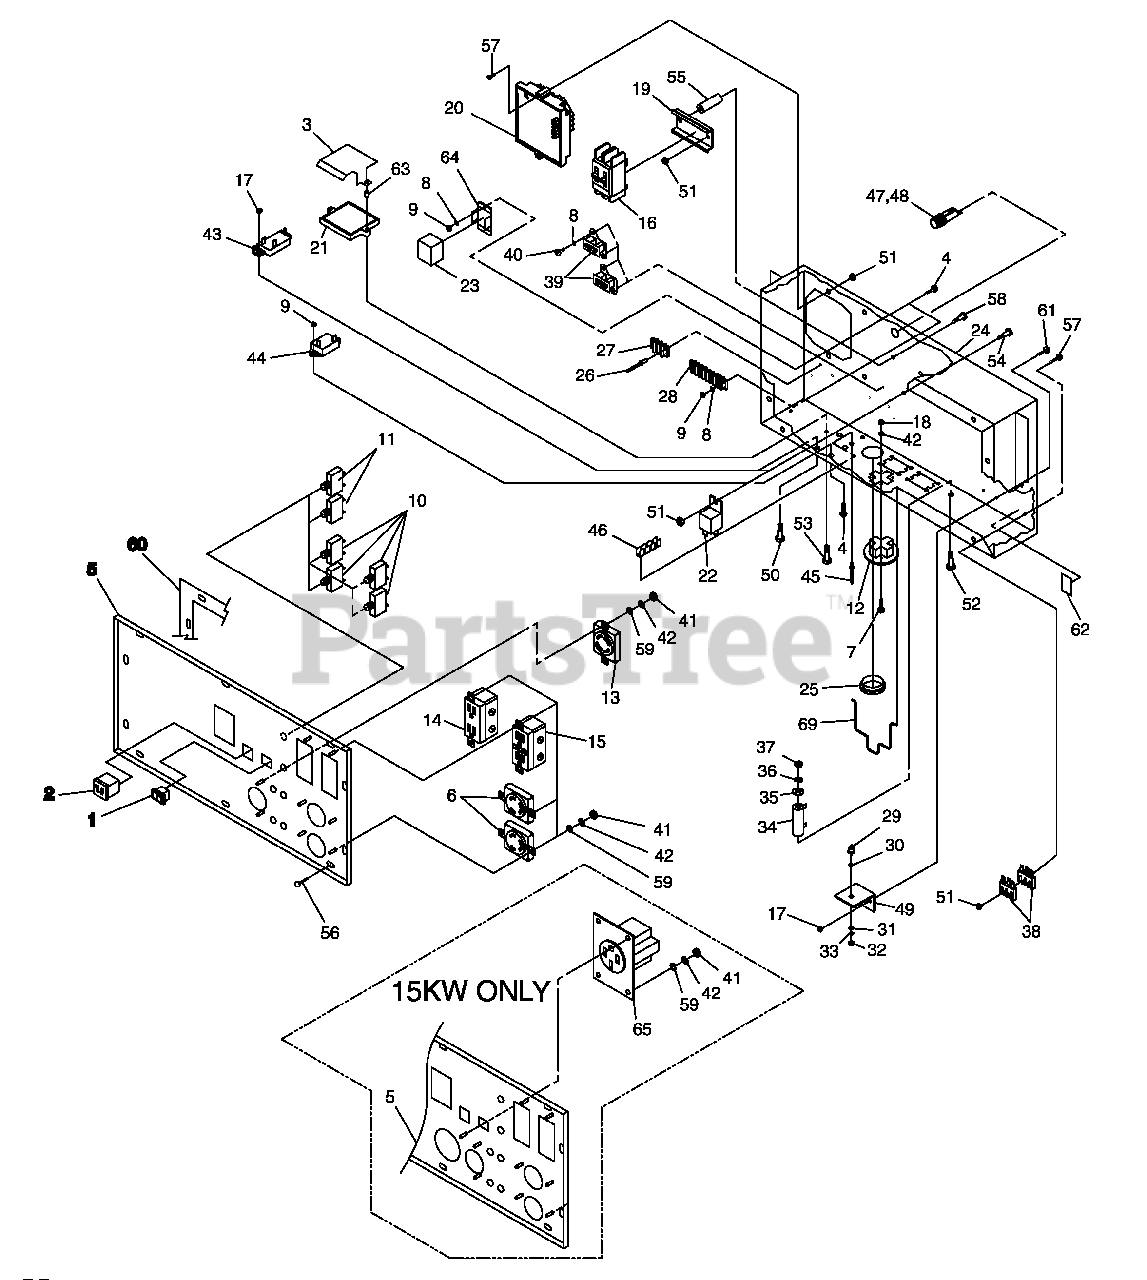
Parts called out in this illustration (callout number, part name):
1	SWITCH, ROCKER -/0
2	OUTLET, 12VDC SNAP
3	COVER, GOVERNOR CONTROL
4	SCREW PPHM M3-0.5 X 12
5	PANEL, SHEET METAL (15 KW)
6	OUTLET 30A 120V RECEPT
7	SCREW SFILHM #8-32 X 5/8 LG (17.5 KW ONLY)
8	WASHER LOCK M3
9	NUT HEX LOCK M3-0.5 NY INS
10	CIRCUIT BREAKER 30A
11	CIRCUIT BREAKER 20A
12	OUTLET 50A 250V (17.5 KW ONLY)
13	OUTLET 30A 125/250V
14	OUTLET 20A 120V DPLX
15	OUTLET 20A 120V GFCI
16	CIRCUIT BREAKER 50A 400V 2POLE
17	NUT HEX M4-0.5 NYINS
18	NUT HEX #8-32 (17.5 KW ONLY)
19	DIN RAIL 59.5mm LONG
20	ASSY PCB VREG AIR COOLED
21	ELECTRONIC GOVERNOR / IDLE CONTROLLER
22	RELAY PNL 12VDC SPST 30A
23	RELAY 3PDT 12VDC
24	CONTROL PANEL BOX (15 KW)
25	BUSHING SNAP
26	RIVET POP .156 X .160-.164 / #20
27	BLOCK TERMINAL 20A 2 X 6 X 1100V
28	BLOCK DOUBLE ROW TERMINAL 8 POSITION
29	RECTIFIER MSC 12A 600V
30	WASHER MICA .203
31	WASHER STEP NYLON .20
32	NUT HEX #10-32
33	WASHER FLAT #10
34	RESISTOR 25R 5% 25W
35	WASHER FLAT 1/4
36	WASHER LOCK M6-1/4
37	NUT HEX M6-1.0 G8
38	RECTIFIER-BATTERY CHARGER
39	TRANSFORMER, IDLE CURRENT
40	SCREW PPHM M3-0.5 X 8
41	NUT HEX M4-0.7 G8 (15 KW)
42	WASHER LOCK M4
43	CIRCUIT BREAKER 6 X 1
44	CIRCUIT BREAKER 10 X 1 12VDC 1/4"QC
45	RIVET POP .125 X .250 SS
46	LUG GROUND 8 TABS
47	HOLDER FUSE
48	FUSE 10A X AGC10
49	HEATSINK
50	SCREW PPHM M4-0.7 X 10
51	NUT HEX LOCK M5-0.8 NYINS
52	SCREW HHC M6-1.0 X 65 G8.8
53	SCREW HHC M5-0.8 X 25 G8.8
54	SCREW HHC M5-0.8 X 10 G8.8
55	SPACER .25 X .50 X 2.5 (17.5 KW)
56	SCREW HHTT M5-0.8 X 10
57	SCREW PPHM M5-0.8 X 30
58	SCREW PPHM M5-0.8 X 80 (17.5 KW)
59	WASHER FLAT #8 (15 KW)
60	GASKET, PORTABLE CONTROL PANEL
61	SCREW PPHM M4-0.7 X 16
62	TAPE ELEC UL PERMACEL
63	NUT TRIC M5-0.8
64	RELAY BASE 3PDT 12VDC
65	OUTLET 50A 125/250V (15 KW ONLY)
69	SPRING RETAINER
